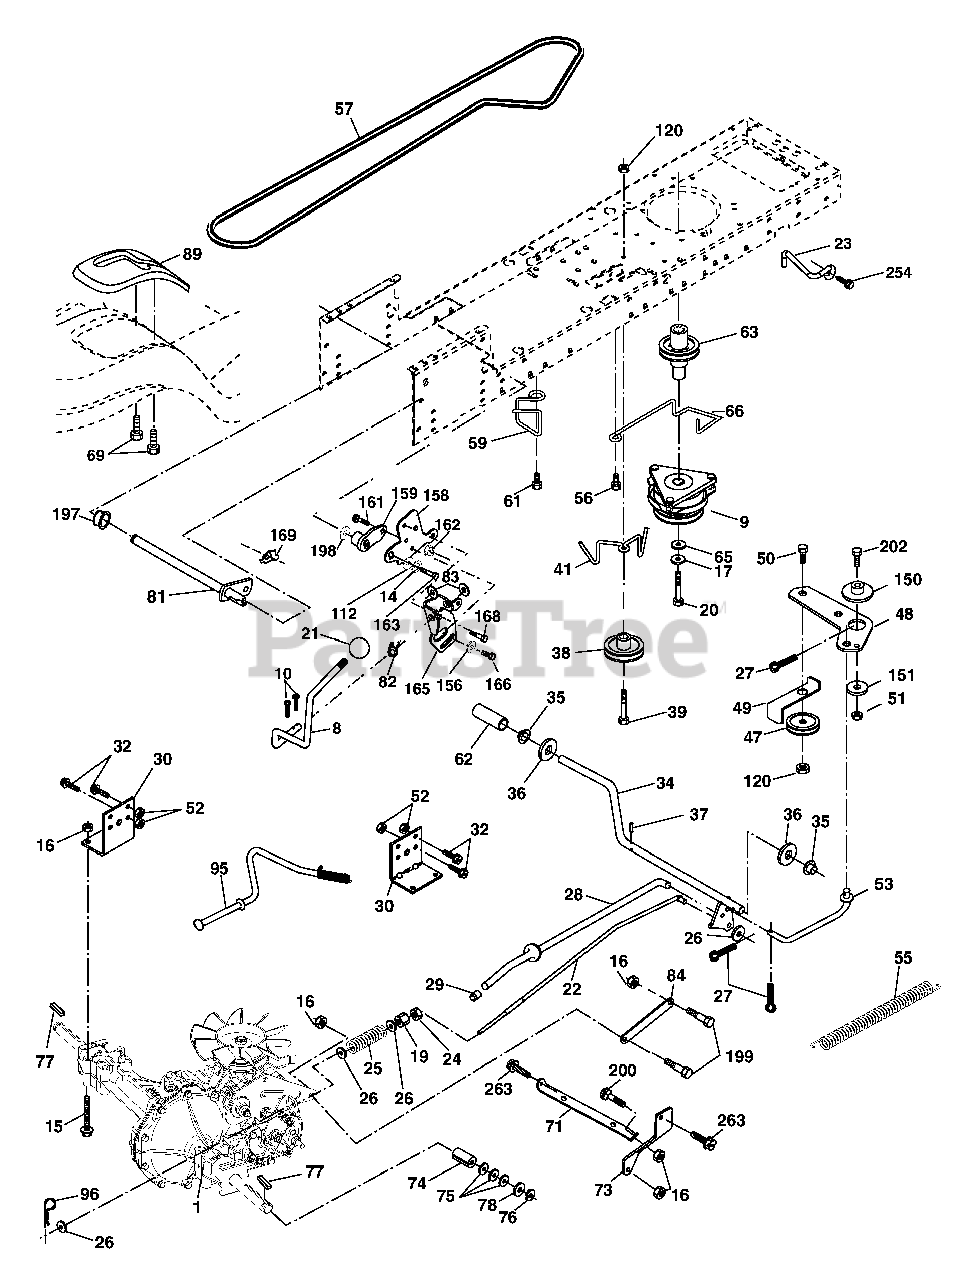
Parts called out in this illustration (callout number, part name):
1	Transaxle, Hydro Gear, Model Number 314-0510 (Order parts from Transaxle manufacturer)
8	Rod Shift Fend.
9	Clutch Electric
10	Pin Cotter 1/8 x 1
14	Washer Lock Hvy 1/4
15	Bolt Hex Flghd 5/16-18 Gr. 5
16	Nut Lock Hex W/Ins. 5/16-18 unc
17	Washer 1-1/2 OD x 15/32 ID x.250
19	Nut Lock Hex W/Wsh 3/8-16 unc
20	Bolt Hex 7/16-20 x 4 x Gr. 5-1.5
21	Knob
22	Rod, Brake
23	Bracket Anti-Rotation
24	Nut, Hex Jam 3/8-16 unc
25	Spring, Brake Rod
26	Washer
27	Pin Cotter 1/8 x 3/4 CAD.
28	Rod, Parking Brake
29	Knob Brake Parking
30	Bracket, Transaxle
32	Bolt Hex Hd 5/16-18 unc x 3/4
34	Shaft, Foot Pedal
35	Bearing, Nylon
36	Washer
37	Pin, Roll
38	Pulley, Composite
39	Bolt Rdhd 3/8-16 unc x 2-3/4 Gr. 5
41	Keeper, Belt Idler Flat
47	Pulley, Idler, V-Groove
48	Bellcrank Clutch Grnd Drw Stl
49	Retainer, Belt
50	Bolt
51	Nut Crownlock 3/8-16 unc
52	Nut, Crownlock 5/16-18 unc
53	Link, Clutch
55	Spring, Return, Clutch
56	Screw 3/8-16 x 1-1/4
57	V-Belt, Ground Drive
59	Keeper, Center Span
61	Screw 3/8-16 x .875
62	Cover, Pedal
63	Pulley, Engine
65	Washer
66	Keeper Belt Engine
69	Screw Hex Wsh Hi-Lo 1/4-1/2 unc
71	Strap Torque LH
73	Strap Torque RH
74	Spacer, Axle
75	Washer 25/32 x 1-1/4 x 16 Ga.
76	E-Ring
77	Key, Square
78	Washer 25/32 x 1-5/8 x 16 Ga.
81	Shaft Assy. Cross Taper
82	Spring Torsion
83	Washer 17/32 x 3/4 x 16 Ga.
84	Link Transaxle
89	Console, Shift
95	Rod Bypass
96	Retainer Spring 1" Zinc/Cad
112	Screw 5/16 - 18 x 5/8
120	Nut Lock Flg 3/8-16 unc
150	Spacer Retainer
151	Washer 13/32 x 2 x 10 Ga.
156	Washer 5/16 ID x 1.0 x .125
158	Bracket Shift Mount
159	Hub Shift
161	Bolt Rdhd Sqnk 1/4-20 x 3/4 Gr. 5
162	Nut Crownlock 1/4-20 unc
163	Bolt Hex Fin 1/4-20 unc x 1 Gr. 5
164	Washer 9/32 x 3/4 x 10 Ga.
165	Bracket Pivot Lever
168	Bolt Shoulder 5/16-18 x .561
169	Plate Fastener Cross Shf.
197	Nyliner Snap-in 5/8 ID
198	Washer Nyl 7/8 ID x .105"
199	Bolt Shoulder 5/16-18 unc
200	Bolt Rdhd Sqnk 5/16-18 unc x 1
202	Bolt Carr Sh 3/8-16 x 1-3/4 Gr. 5
254	Screw 3/8-16 x 1
263	Screw 3/8-16 x .75
